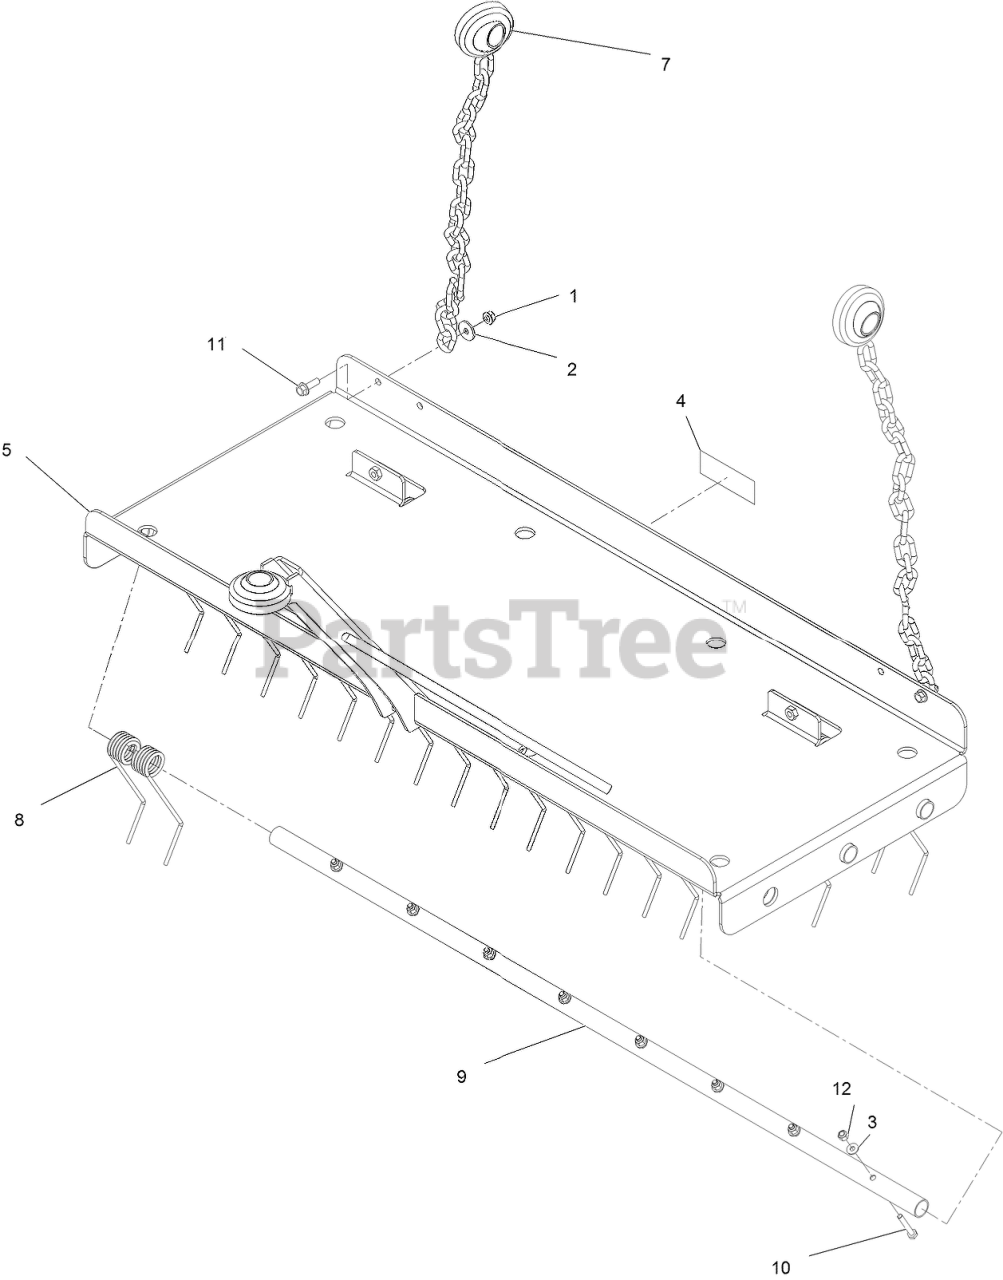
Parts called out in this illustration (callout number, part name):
1	NUT-HF, NI
2	WASHER-FLAT
4	DECAL-WARNING
5	Platform-Rake [blk-Txt]
7	RAKE BALL SOCKET AND CHAI
8	SPRING TINE\NGG187DT-NB
9	RAKE TUBE
10	SCREW-HH
11	SCREW-HH
12	NUT-LOCK, NI
